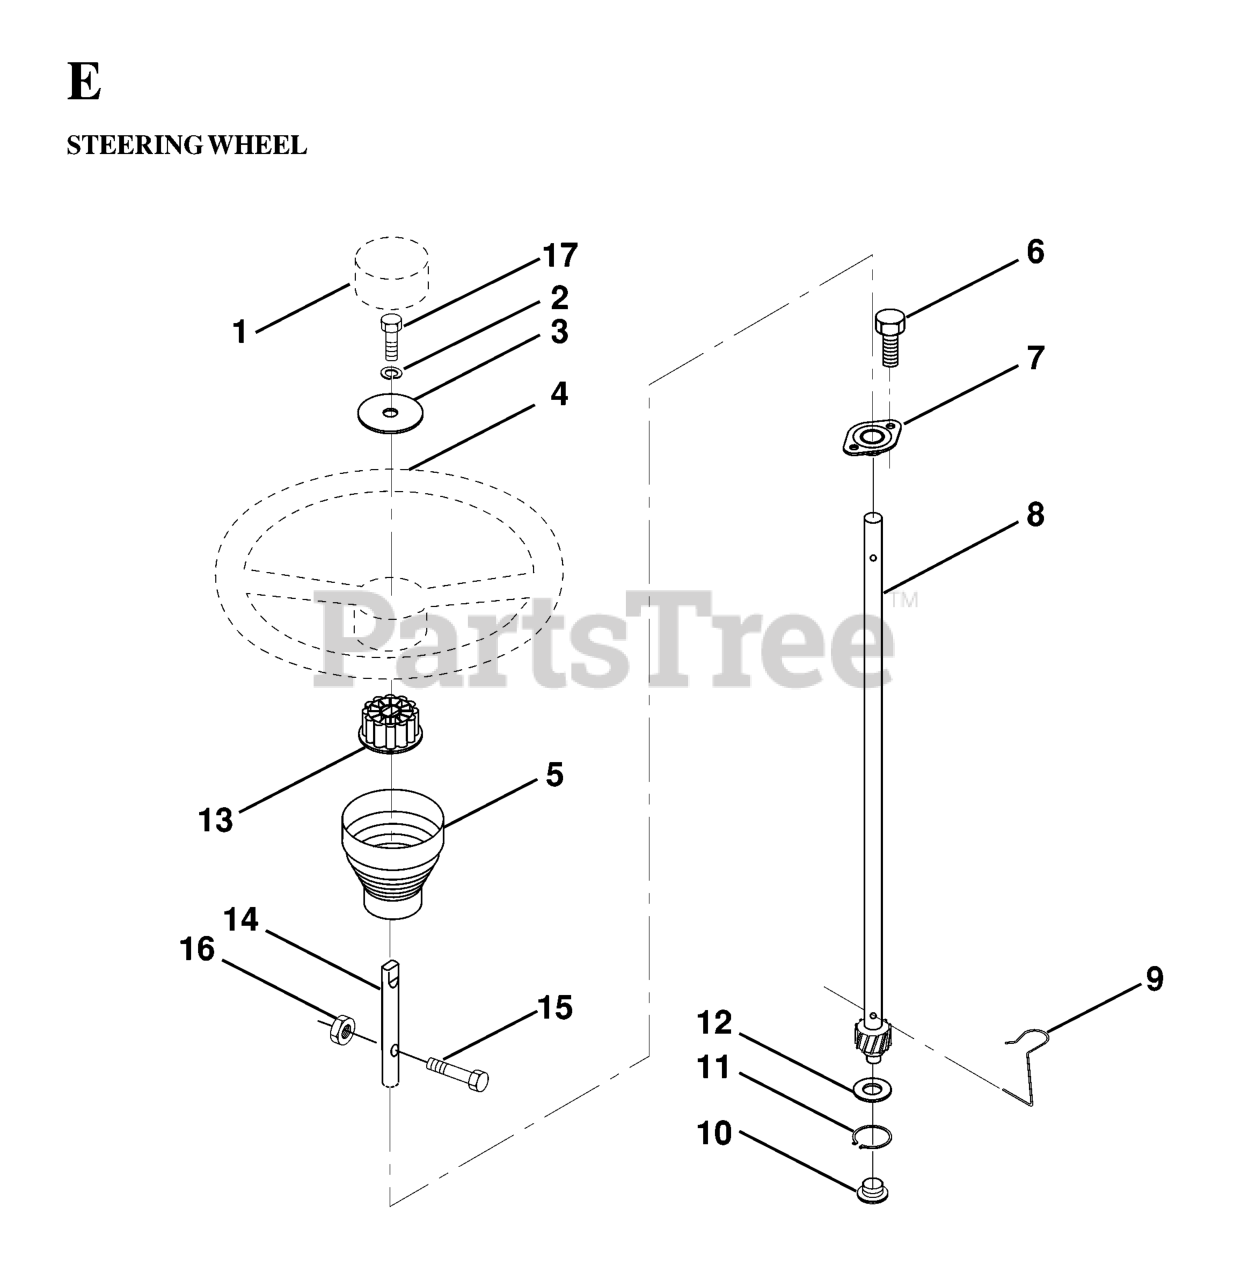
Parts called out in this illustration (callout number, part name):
1	INSERT,STR WHEEL
2	WASHER, LOCK 3/8
3	WASHER T
4	STEERING WHEEL
5	STEERING SLEEVE
6	SCREW.TT.#10-32X.5.3/8.FLANGE
7	BUSHING
8	STEERING SHAFT
9	STEERING CLIP
10	BUSHING STEER LWR
13	ADAPTER LT
14	EXT SHAFT STEERING
15	BOLT.5/16-18X1-1/4 FULL.THREAD
16	NUT.71038.31-18.HEX.NYLOCK
